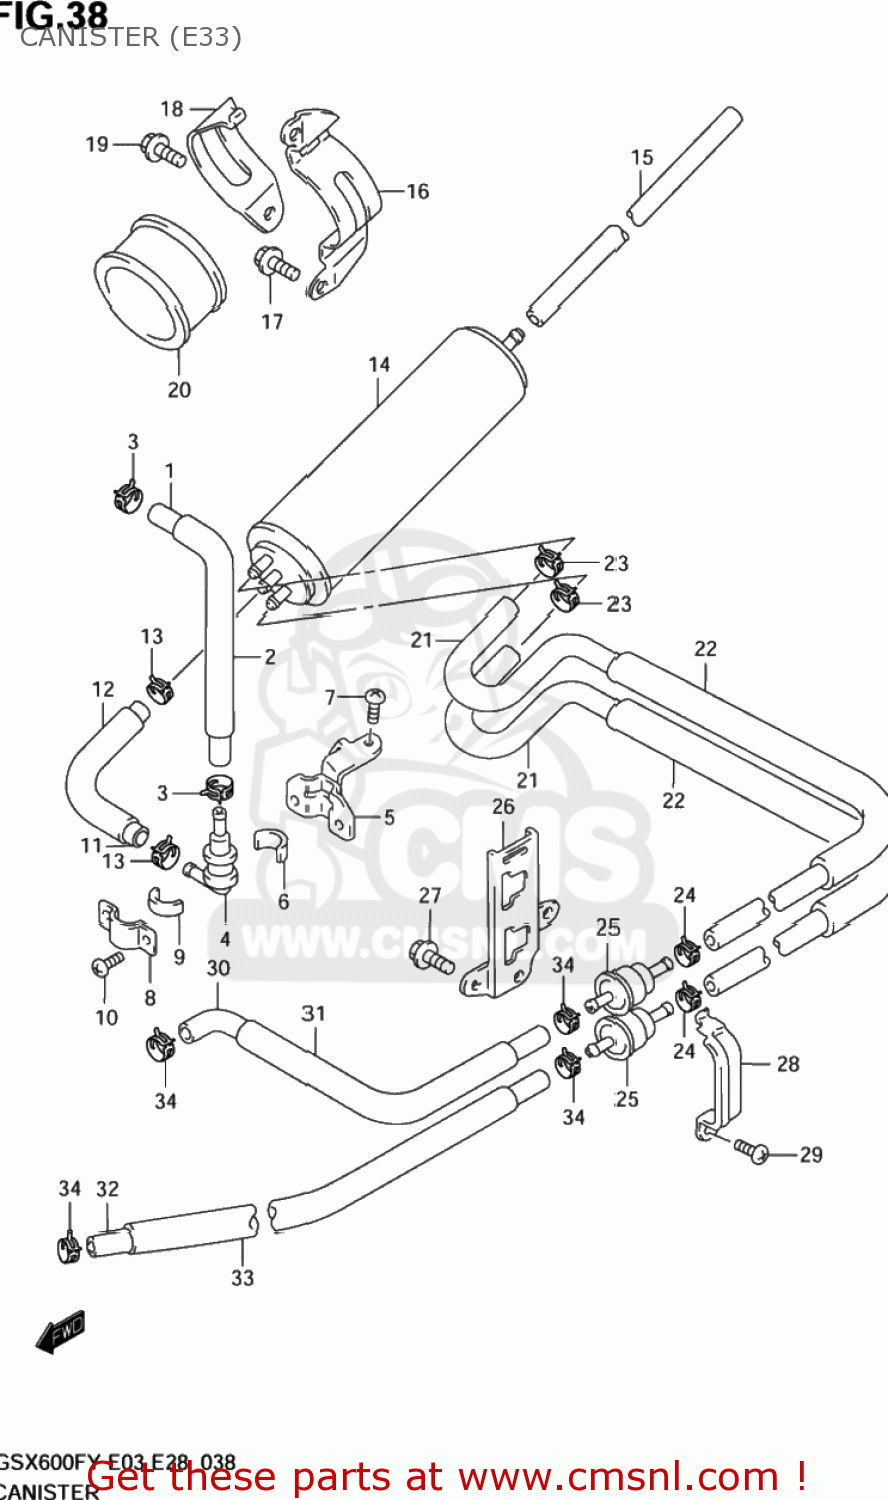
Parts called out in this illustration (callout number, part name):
1	HOSE(5.4X11.4X600)
2	PROTECTOR(14.5X15.5X600)
3	CLIP
4	VALVE,FUEL TANK BREATHER
5	PLATE,BREATHER VALVE
6	CUSHION
7	SCREW
8	PLATE,FUEL TANK BREATHER NO.2
9	CUSHION
10	SCREW 6X12
11	HOSE,VALVE & CANISTER CHARGE
12	PROTECTOR(14.5X15.5X600)
13	CLIP
14	CANISTER ASSY,CHARCOAL
15	HOSE(7X12X600)
16	BRACKET,CANISTER MOUNTING
17	BOLT
18	HOLDER,CANISTER
19	SCREW 6X12
20	CUSHION,CANISTER
21	HOSE,CSTR & PURGE VALVE
22	PROTECTOR(14.5X15.5X600)
23	CLIP
24	CLIP
25	VALVE,CANISTER PURGE
26	BRACKET,CANISTER PURGE VALVE
27	BOLT
28	HOLDER,CANISTER PURGE
29	SCREW
30	HOSE(5.4X11.4X2000)
31	HOSE
32	HOSE(5.4X11.4X2000)
33	PROTECTOR(14.5X15.5X600)
34	CLIP
